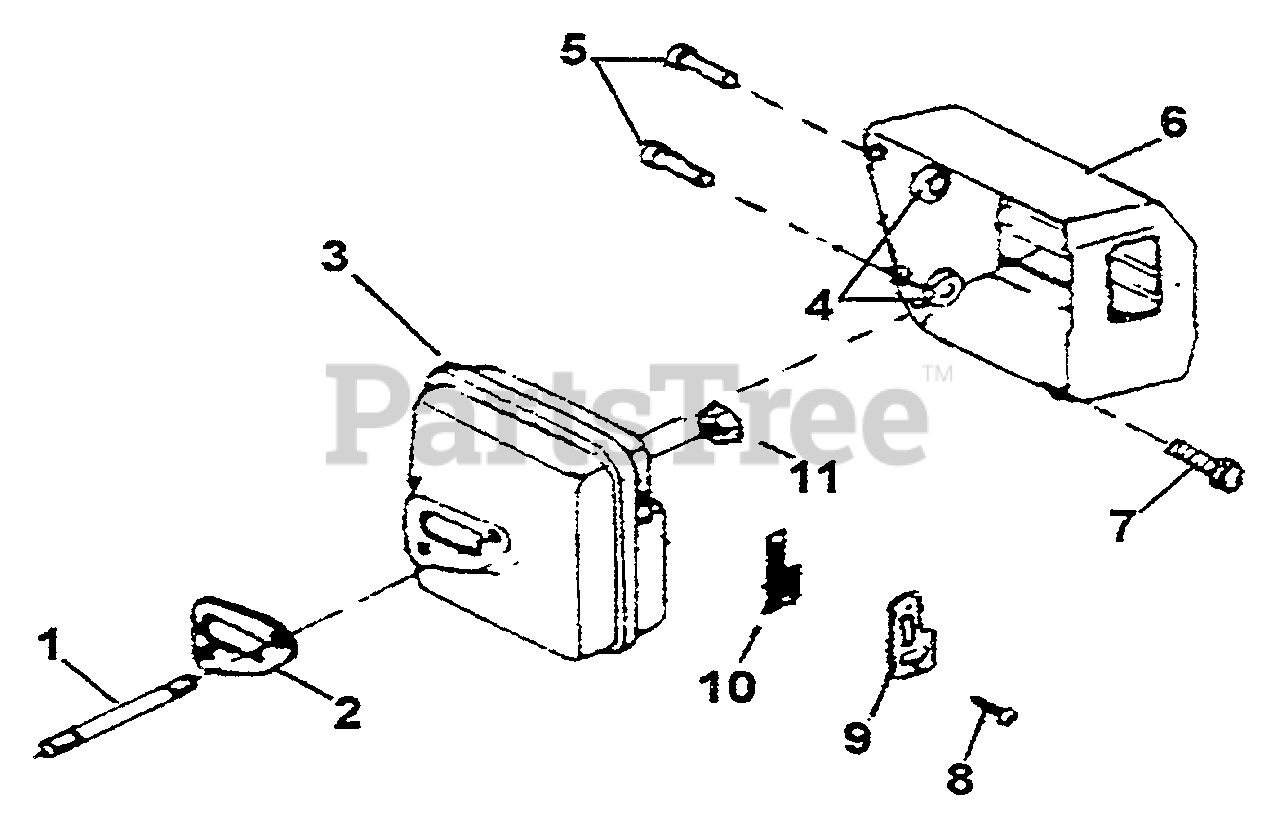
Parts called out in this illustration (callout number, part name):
2	GASKET, MUFFLER
3	MUFFLER ASSY
9	COVER, SPARK ARRESTOR
10	SCREEN, SPARK ARRESTOR
